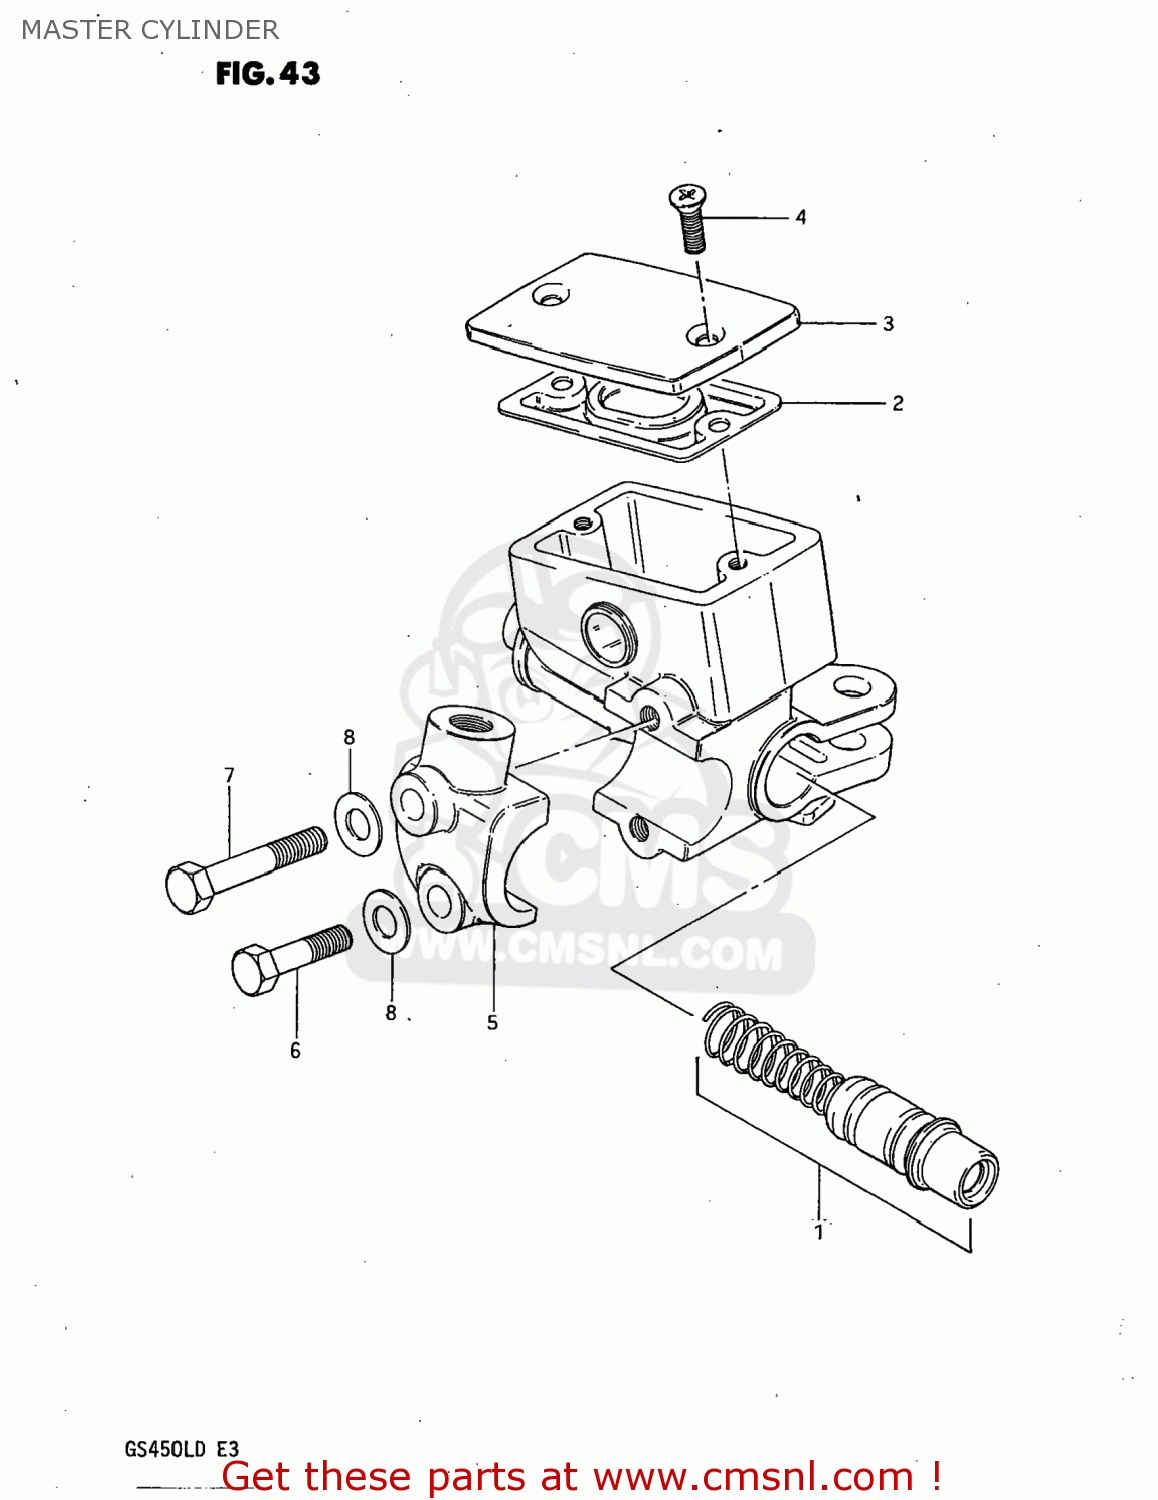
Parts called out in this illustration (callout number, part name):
1	PISTON & CUP SET
2	3
3	CAP
4	SCREW
5	HOLDER
6	BOLT
7	BOLT 6X40
8	LOCK WASHER
